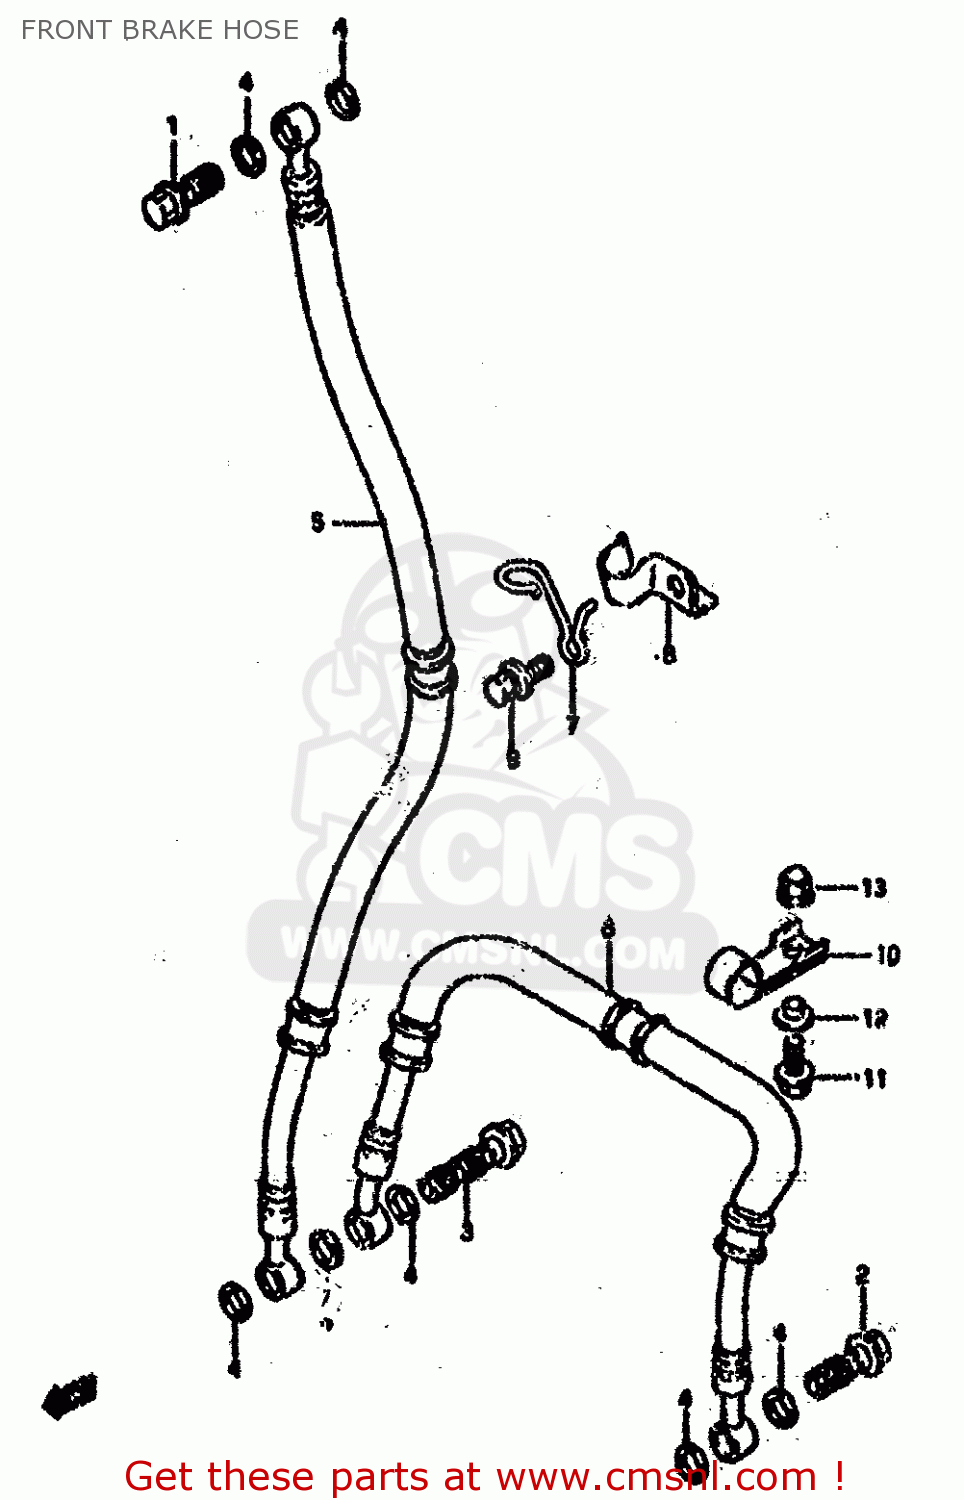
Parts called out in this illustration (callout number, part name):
1	BOLT UNION
2	BOLT UNION
3	BOLT UNION
4	WASHER(10X15X1.5)
5	HOSE,FR BRAKE NO.1
6	HOSE COMP,FRONT BRAKE
7	GUIDE,FR BRAKE HOSE
8	CLAMP,FR BRAKE HOSE UPR
9	BOLT
10	CLAMP,FR BRAKE HOSE NO.2
11	BOLT
12	WASHER
13	NUT
